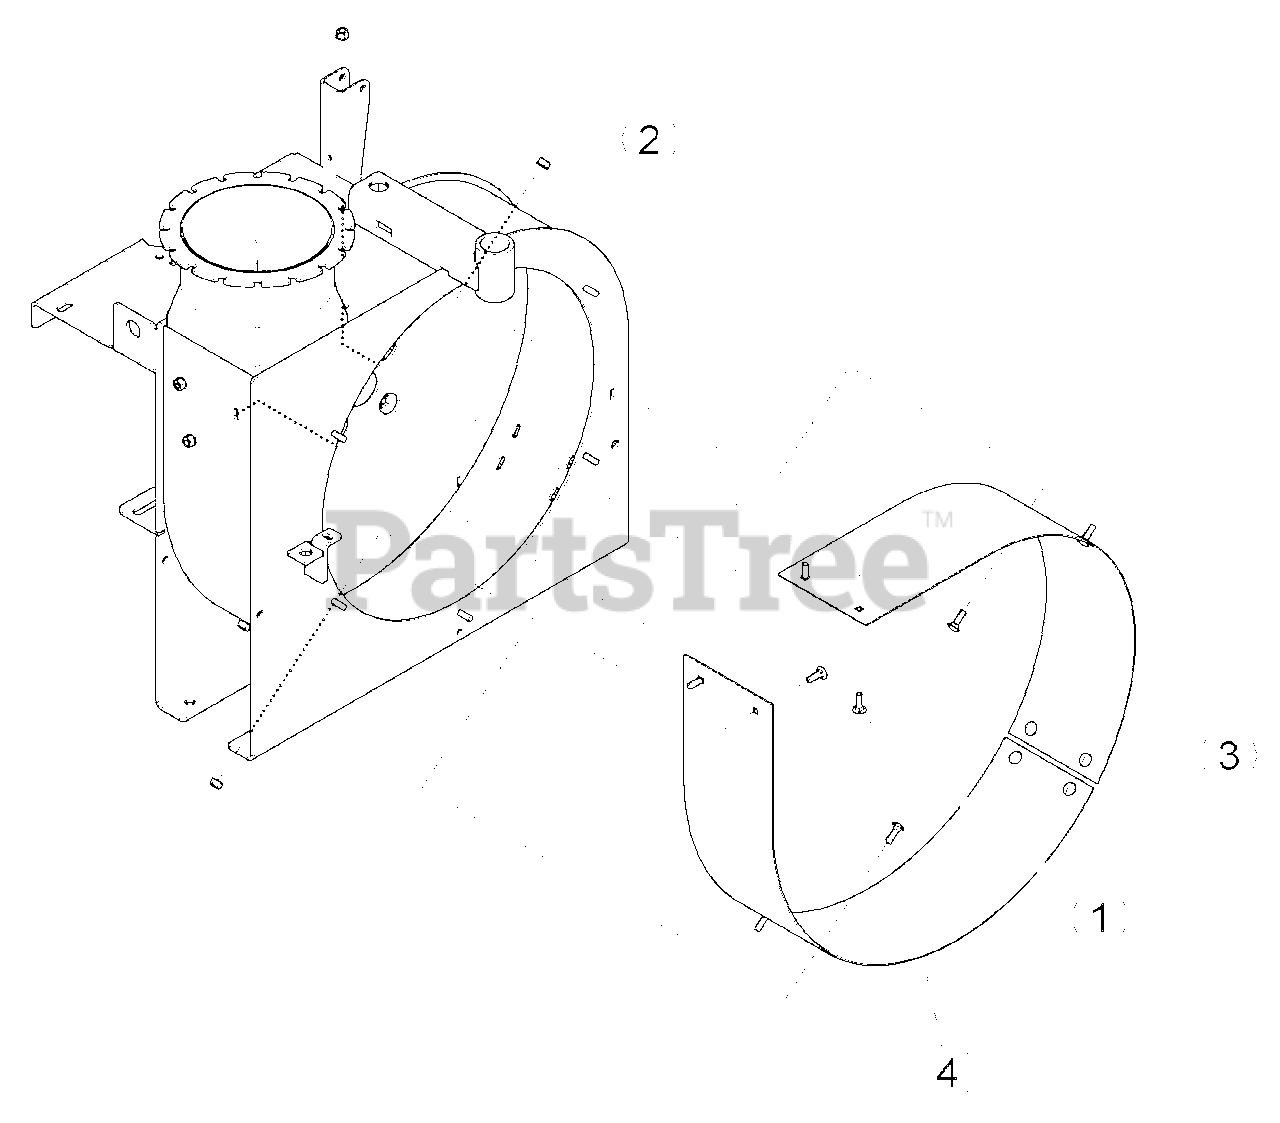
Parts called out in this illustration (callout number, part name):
1	BOLT, 5/16 X 1 GR5 CRG ZP
2	NUT, 5/16-18 NYLOCK FLANGE
3	WRAP, HOUSING FAN
4	WRAP, HOUSING FAN
